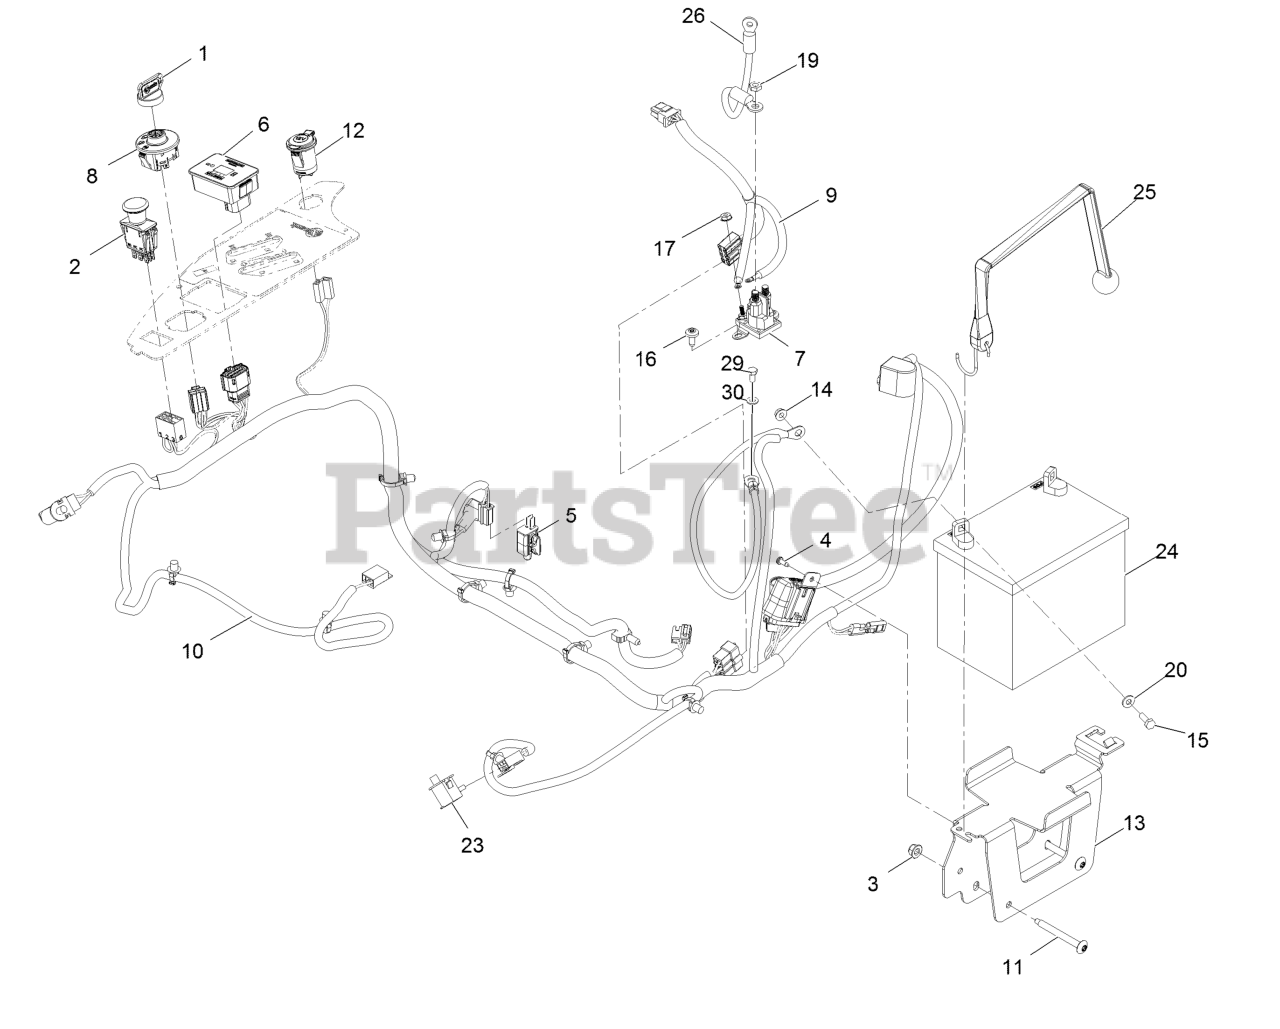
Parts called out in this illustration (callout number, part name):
1	Key-Ignition
1	Key-Exmark Logo
2	Switch-PTO
3	Nut-Nyloc 5/16-18 Flg
4	Screw-Tph #10-24 X 1/2 Tf
6	Module ASM
7	Solenoid
8	Switch-Ignition
9	Adapter-Harness, Wire
10	Harness-Wire
11	Screw-Truss HD 5/16-18 X 2 3/4 Torx Plus
12	Port-Power, 12V
13	Tray-Battery
14	Nut-Whizlock 1/4-20
15	Screw-HH 1/4-20 X 3/4
16	Screw-1/4-20 X .65 Torx Plus
17	Nut-Keps 10-32 Unf Yz
19	Nut-Jam 5/16-24
20	Washer-1/4 SAE
24	Battery (300 CCA, Wet)
25	Strap-Bungee
26	Cable-Battery, Positive
29	Screw-HH
30	Washer-5/16 SAE
